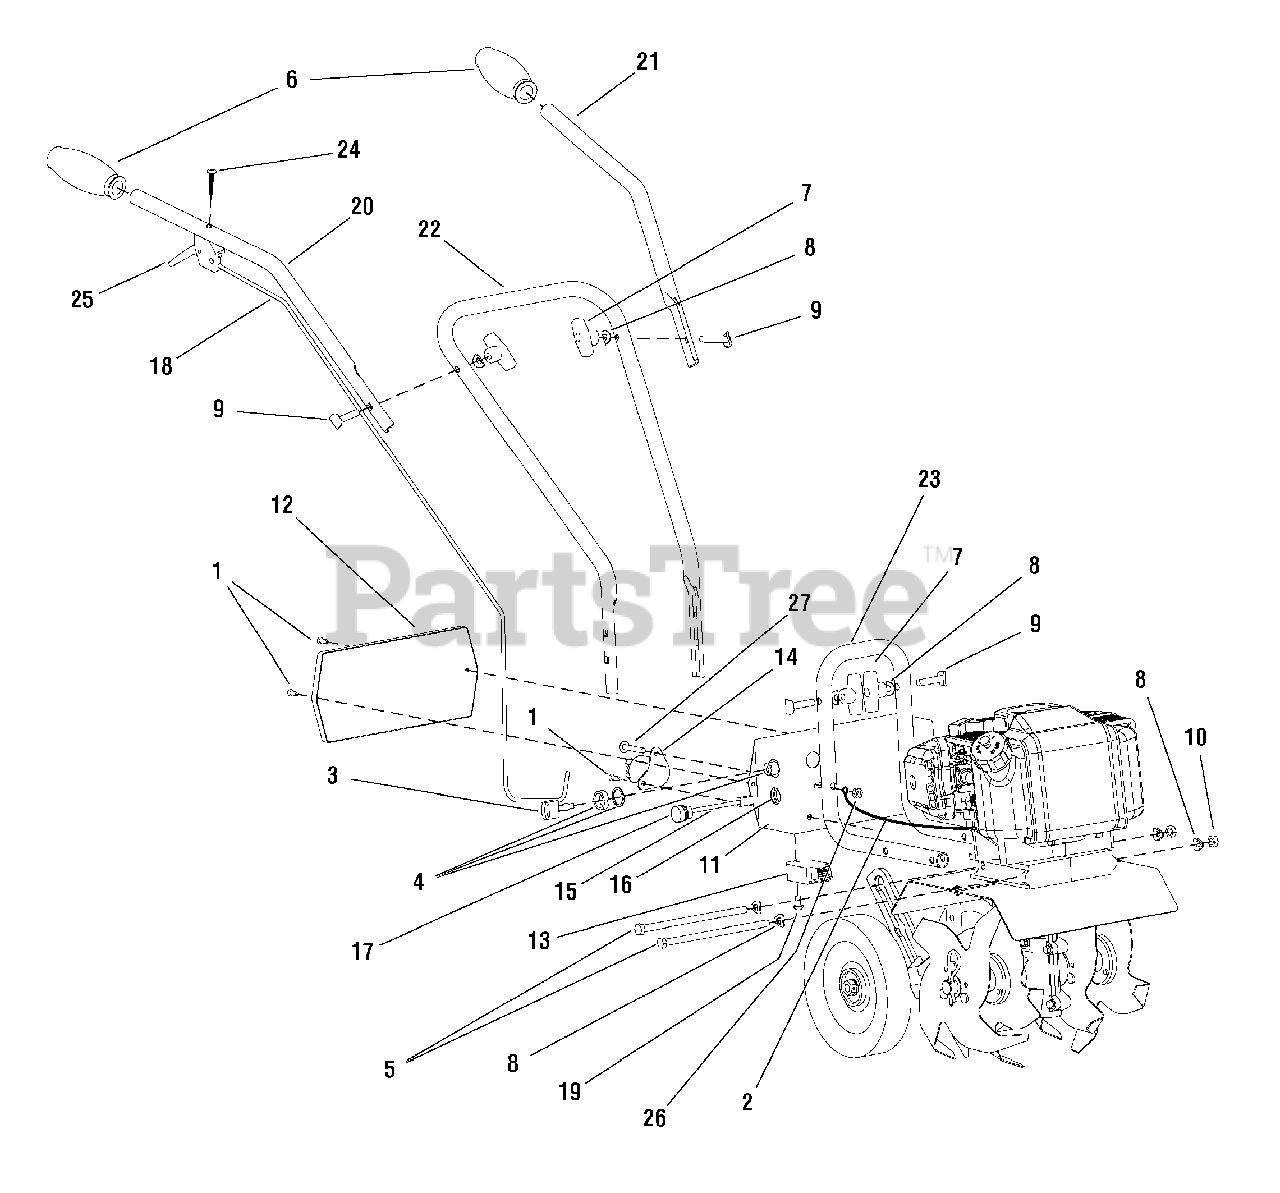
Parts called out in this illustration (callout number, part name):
1	BOLT, M5 x 12mm
2	GROUND WIRE
3	KEY ONLY
4	KEY SWITCH
5	BOLT, Hex Head, M8 x 1.25 x 160mm
6	GRIP, Handlebar, Flangeless, 1"
7	NUT, T-Handle
8	WASHER HANDLE
9	BOLT, Handle Clamp
10	NUT, Hex Head, M8 x 1.25
11	BATTERY BOX MC43e
12	COVER, Battery Box
13	VOLTAGE RECTIFIER
14	SOLENOID
15	CHARGER PIGTAIL
16	NUT, Charger Pigtail
17	CAP, Charger Pigtail
18	THROTTLE CABLE
19	BOLT, Pan Head, M6 x 1mm x 12mm
20	HANDLEBAR, Upper Right
21	HANDLEBAR, Upper Left
22	HANDLEBAR, Middle
23	HANDLEBAR, Lower
24	BOLT, Phillips Truss Head ZN, 10-24 x 1-1/4
25	TRIGGER ASSEMBLY, Long Throw w/o Cable
26	NUT, Bi-Way Lock, 1/4-20
27	BOLT, Phillips Truss Head ZN, 1/4-20 x 1-1/2
